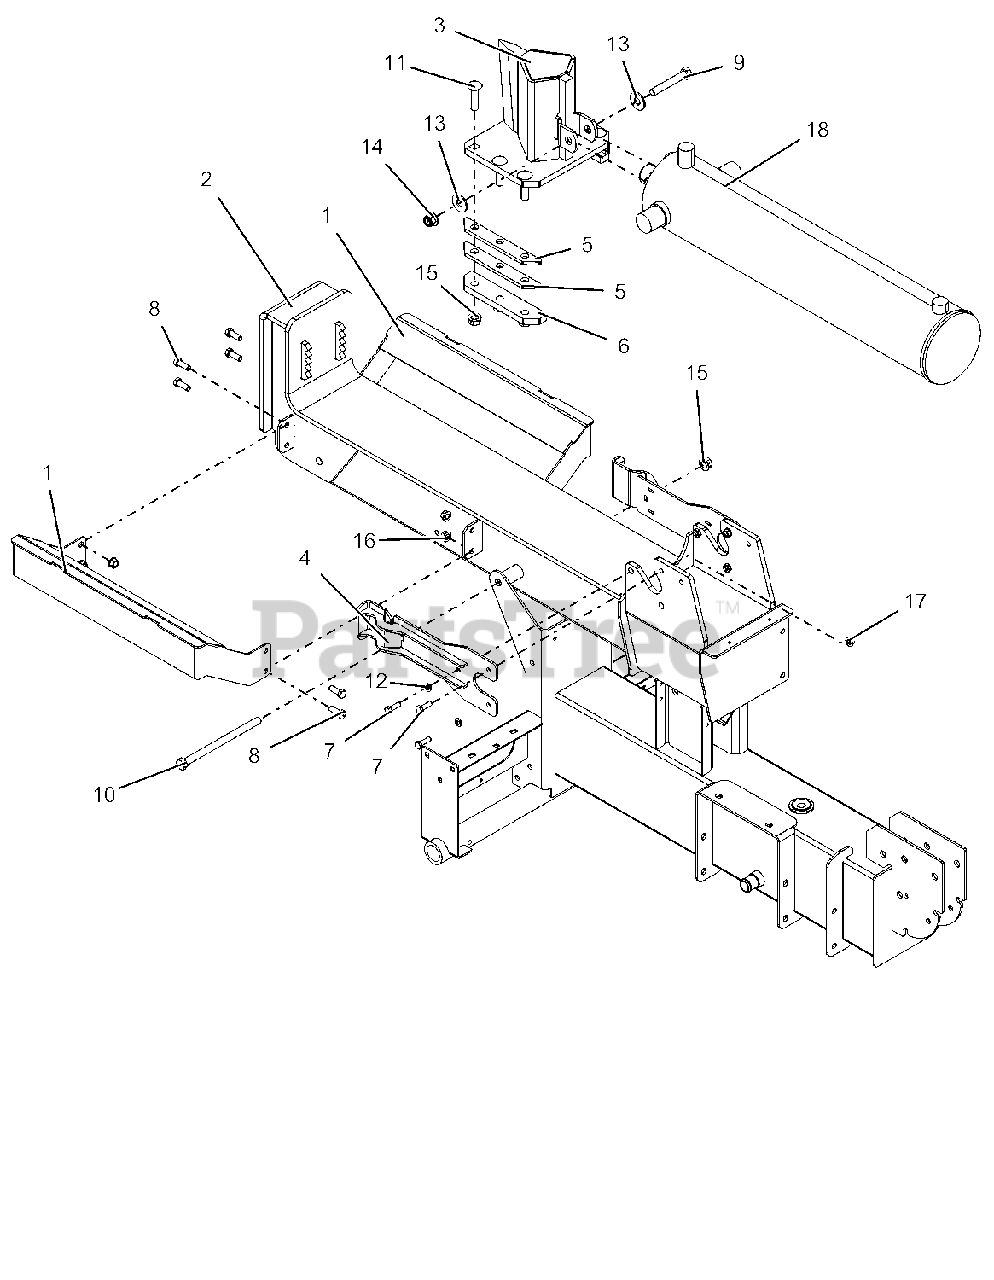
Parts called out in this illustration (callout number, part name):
1	WLDMT, CRADLE, LOG SPLITTER
2	WLDMT, BEAM - 27/34T SPLITTER
3	WMT, WEDGE - SPLITTER
4	WLDMT, PLATE - STRIPPER
5	SPACER, WEDGE
6	RETAINER,WEDGE
7	@BLT-HEX .31-18X1.00 GR5 YWZC
8	@BLT-HEX .38-16X1.00 GR5 YWZC
9	@BLT-HEX .50-13X3.25 GR5 YWZC
10	@BLT-HEX .50-13X7.50 GR5 YWZC
11	BLT-RDHDSQNKFTH.50-13X2 G8YWZC
12	WSHR-LK .312X.097 HVY YWZC
13	@WSHR-FL-STL.563X1.38X.109YWZC
14	@NUT-LK-NYL-FLG .50-13 YWZC
15	NUT-LK-CTR-FLG .50-13 YWZC
16	@NUT-LK-TOP-FLG .38-16 YWZC
17	@NUT-LK-TOP-FLG .31-18 YWZC
18	CYLINDER, 5' W/DECALS
